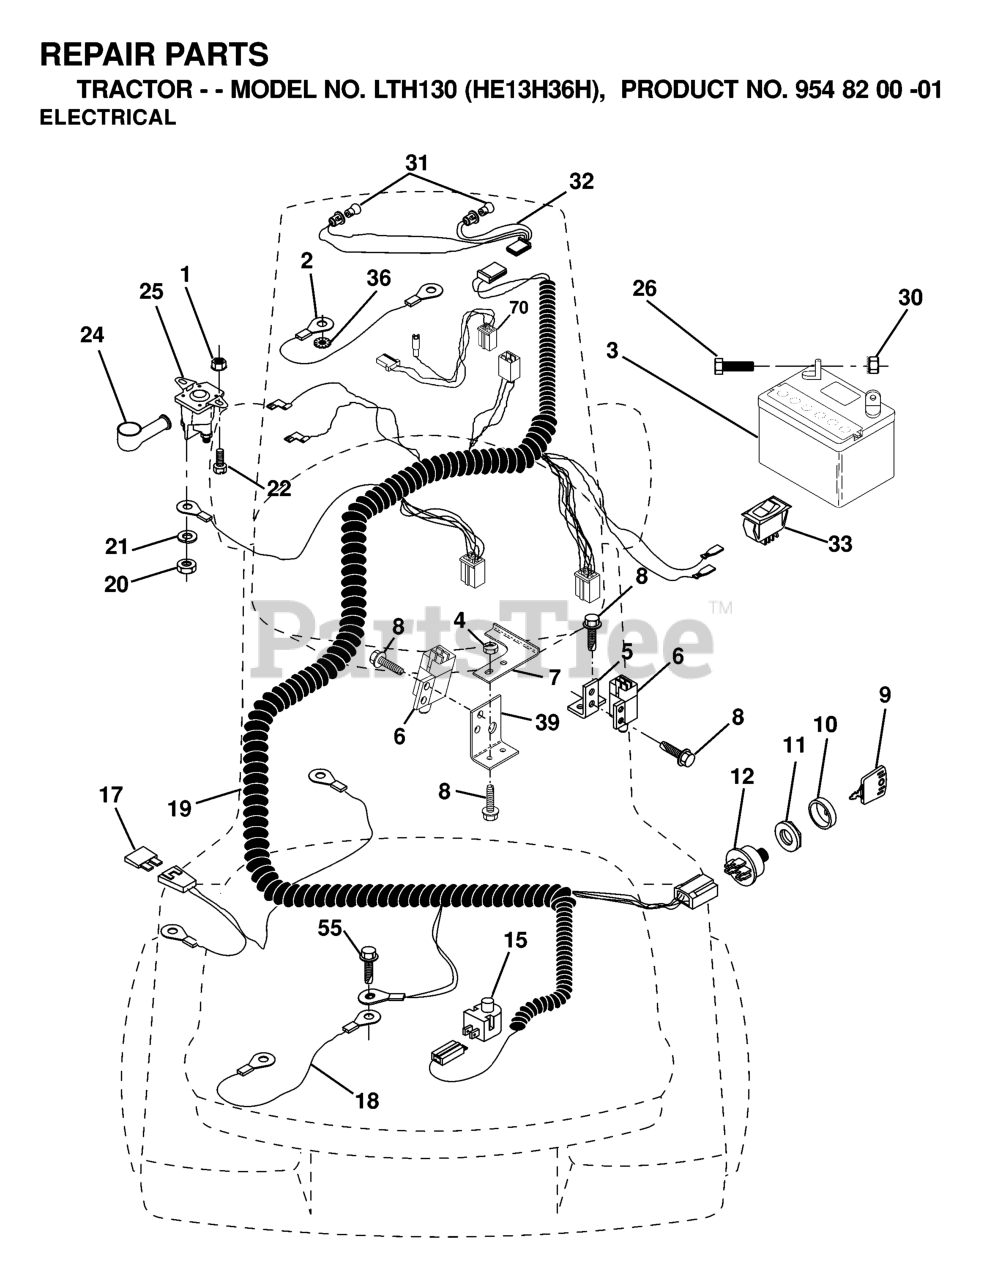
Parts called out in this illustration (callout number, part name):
2	DRAWBAR
3	SCREW 3/8-16X3/4
5	BUMPER.RUBBER.HOOD
9	DASH
10	BOLT D
11	PANEL DASH LH
13	DASH PANEL RH
17	HOOD
18	BUMPER HOOD T
20	PLATE MTG
23	BUSHING.SNAP.NYL.BLK.
25	WASHER
26	NUT
28	GRILL
29	LENS
30	FENDER FOOTREST
31	BRACKET.SUPPORT.FENDER
37	Screw 5/16-18 x 1/2 Hex, Self Tapping 5/16-18 x 1/2
38	BRACKET
51	LOCKNUT.NYLOC.1/4-20
53	BRACKET PNT PICK OFF LT/PL
57	BOLT
58	AIR DUCT P/L/LT
60	Bolt - Rd. Hd. Sq. Neckiage 3/8 16 x 3/4
64	DASH LOWER
68	NUT
71	NUT.CROWNLOCK.1/4
134	ROD SUPPORT HOOD LT/PL HUS.
142	PLATE
143	BRACKET, SWAY BAR
144	BRACKET FOOTREST
145	ROD PIVOT CHASSIS/HOOD
206	SHOULDER BOLT 5/16-18TT
208	SCREW 3/8-16X1/2
212	INSERT LENS REFLECTOR
